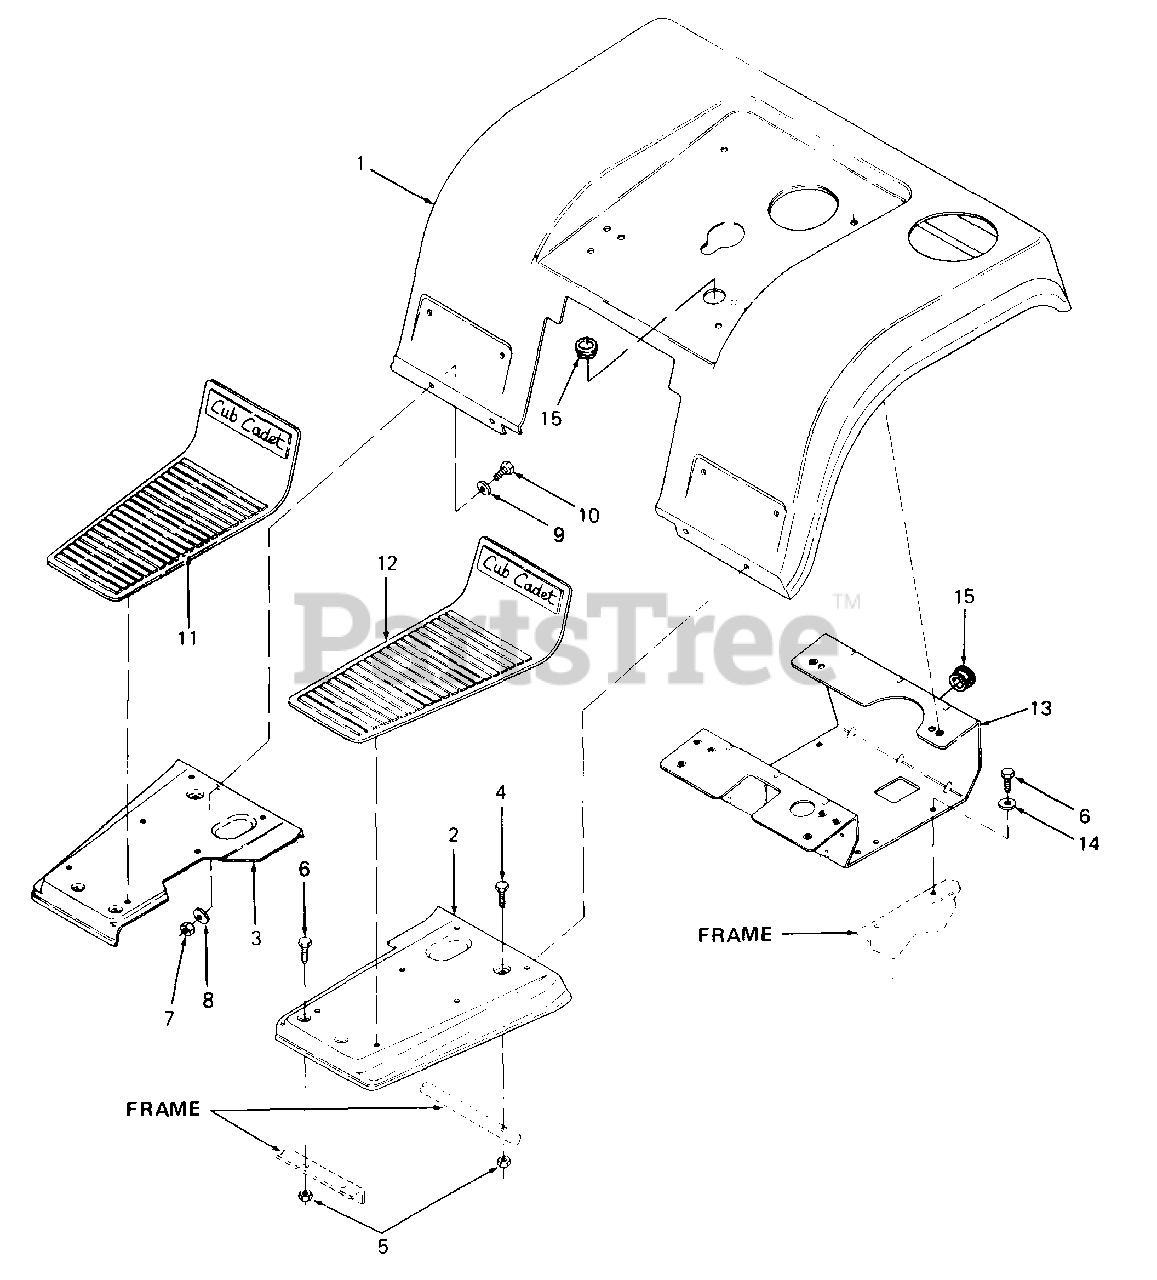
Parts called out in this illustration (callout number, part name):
5	Nut, Hex Center Lock, 5/16-18 GR5
6	Screw, Hex Cap, 5/16-18 X .62 Lg GR5
7	Nut, Hex Patch Lock, 1/4-20
8	Washer, Bell, .265 X .75 X .062 Thk
9	Washer, Flat, .281 X .73 X .063 Thk
10	Screw, Hex, Cap, 1/4-20 X .50 Lg GR5
11	Foot Pad - RH
12	Foot Pad - LH
14	Washer, Flat, .34 X .69 X .062 Thk
15	Bushing, Snap
